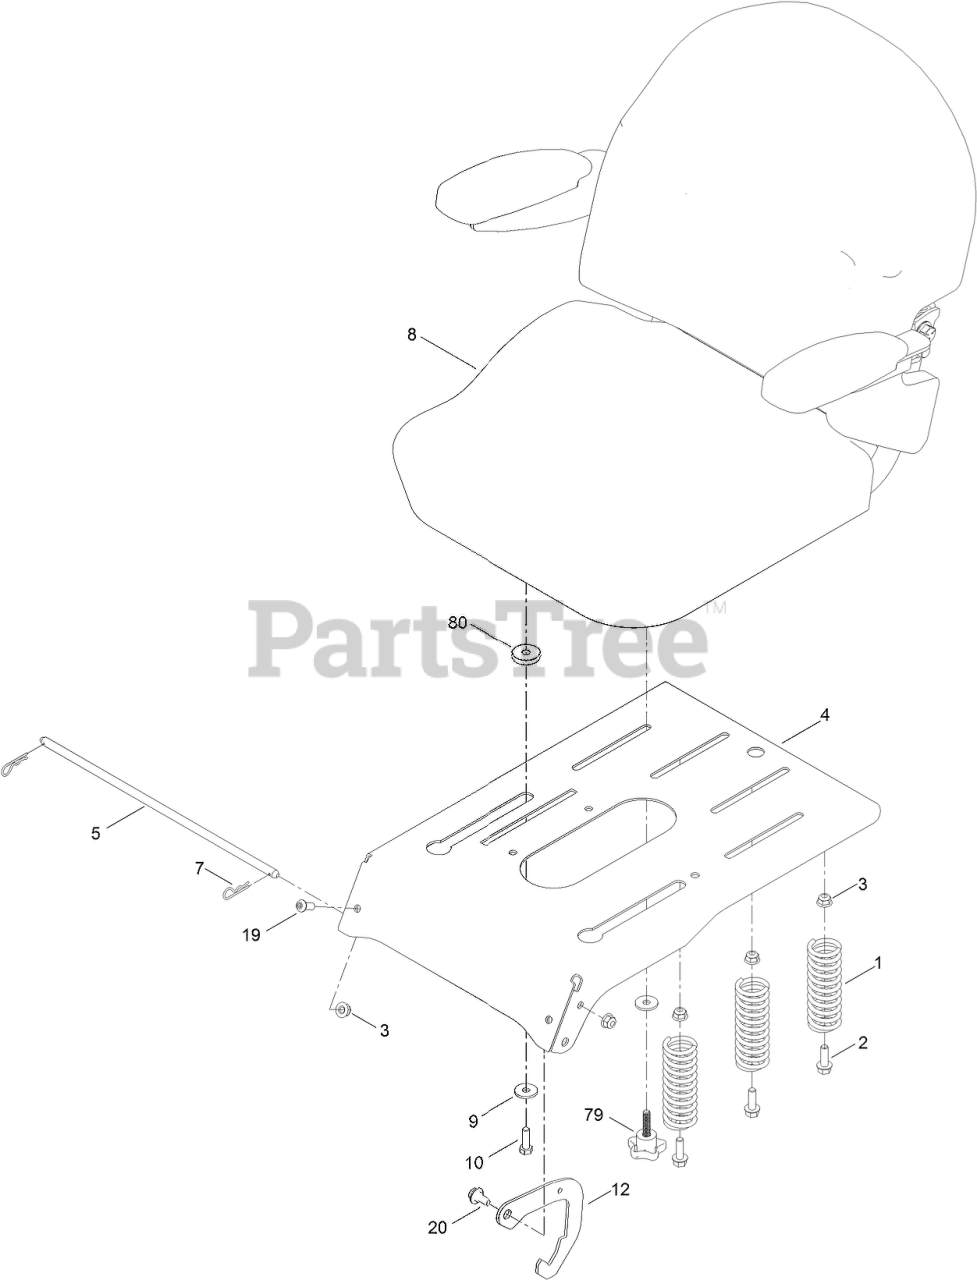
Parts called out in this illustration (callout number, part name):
1	SPRING-COMPRESSION
2	SCREW-HHF
3	NUT-HF, NI
4	PAN-SEAT, DELUXE
5	ROD-PIVOT, NARROW
7	PIN-COTTER
8	Seat ASM
9	WASHER-FRICTION
10	SCREW-HH
12	SEAT LATCH
19	SCREW-HSBH
20	SCREW-SHOULDER
80	SPACER-STEPPED
